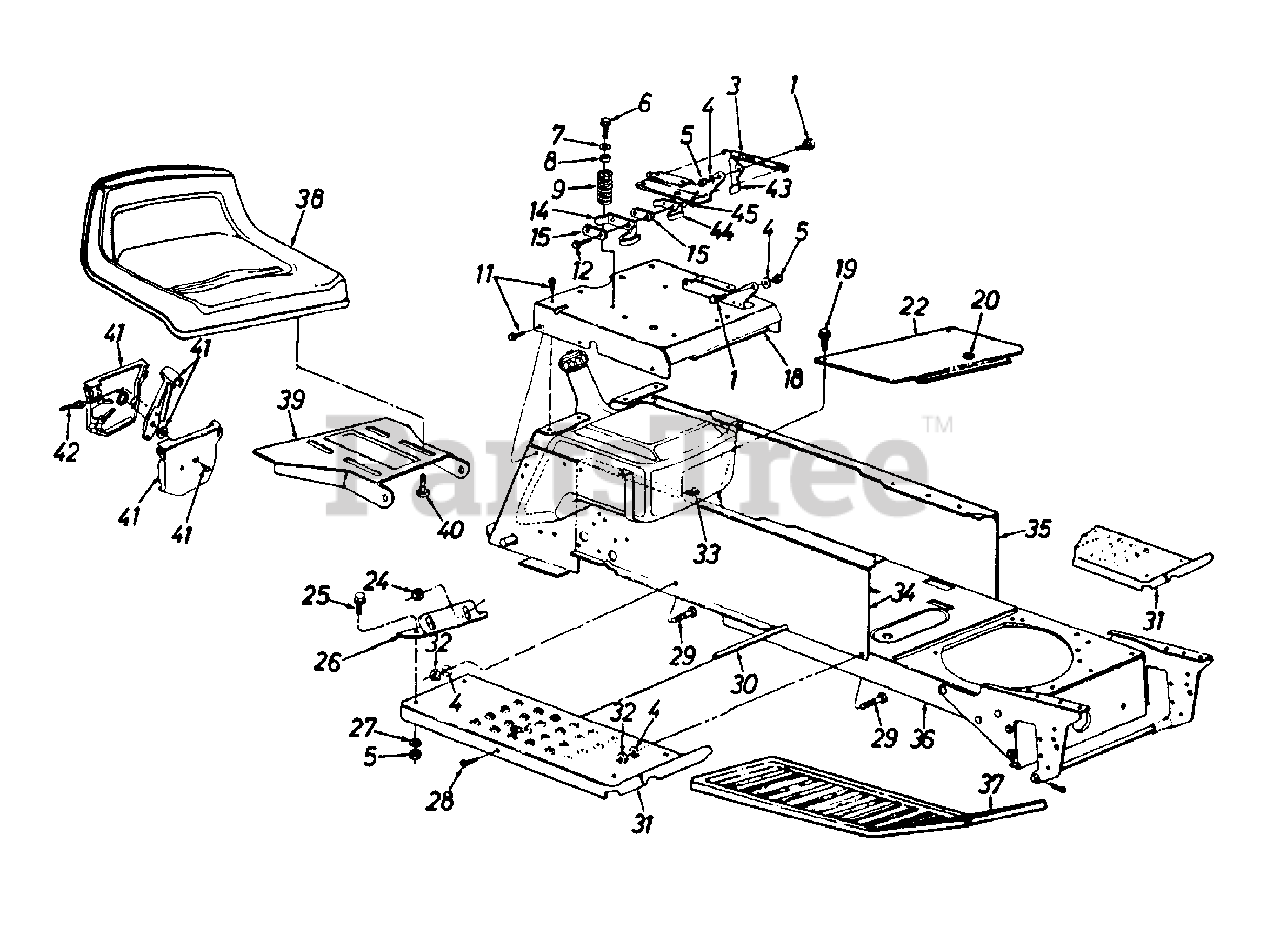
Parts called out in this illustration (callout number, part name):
1	Shld. Bolt .437" Dia. x .162"
3	Ext. Spring 5.31" Lg.
4	L-Wash. 5/16" I.D.
5	Hex Nut 5/16-18 Thd. (Gr. 5)
6	Hex Wash. Hd. Tap Scr.5/16-18 x .7"
7	Fl-Wash. .344" I.D.
8	Bushing
9	Compression Spring
11	Hex Wash. Hd. AB-Tap Scr.5/16 x .75
12	Hex Wash. Hd. AB-Tap Scr.#8 x .5"
14	Spring Switch
15	Insulator Plate
18	Seat Plate
19	Truss Mach. B-Tap Scr.#10 x .5" Lg.
20	Snap Bushing
25	Hex Bolt 5/16-18 x .75" Lg.
28	Truss Mach. Scr. 5/16-18 x .75" Lg.
29	Rib Neck Bolt 5/16-24 x .75" Lg.
30	Running Board Rod
33	Speed Nut #10Z
38	Seat
40	Hex Tap Scr. 3/8-16 x .62" Lg.
41	Throttle Control Box Ass'y.
42	Throttle Control Wire 35" Lg.
43	Seat Lift Bracket
44	Seat Spring Switch
45	Insulator Boss Plate
